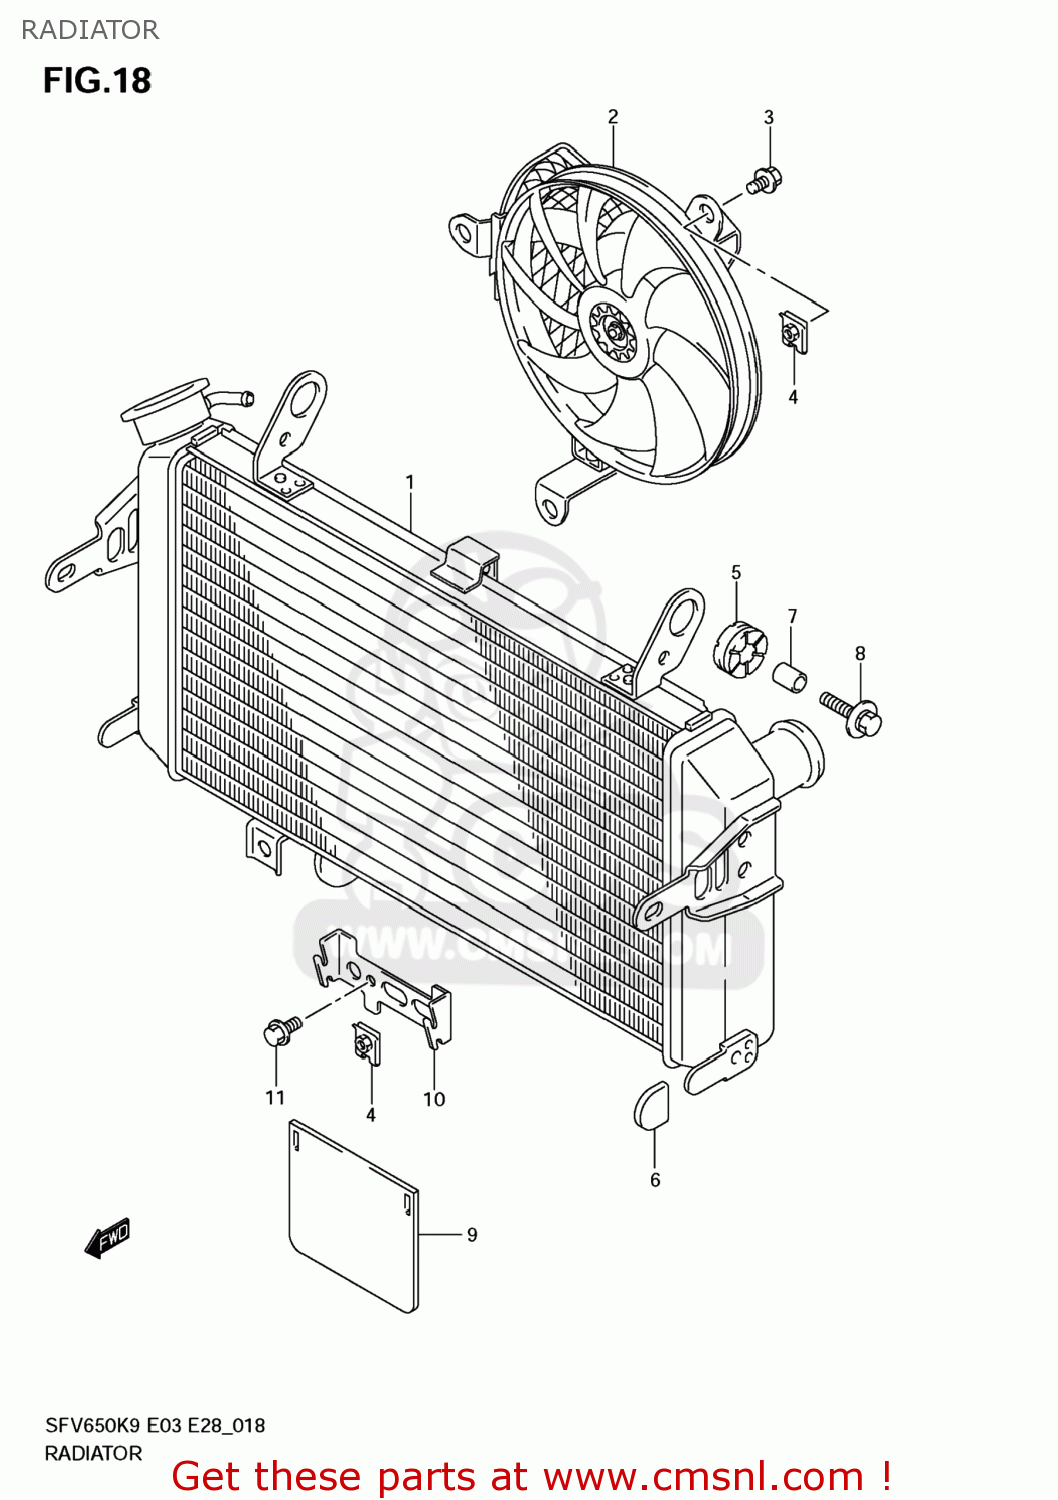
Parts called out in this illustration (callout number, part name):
1	RADIATOR ASSY,WATER
2	FAN ASSY,RADIATOR
3	BOLT,FAN ASSY
4	NUT,FAN ASSY
5	CUSHION
6	CUSHION
7	SPACER(6.5X10X12)
8	BOLT(6X25)
9	RUBBER,RADIATOR UNDER
10	BRACKET,RADIATOR UNDER RUBBER
11	BOLT
